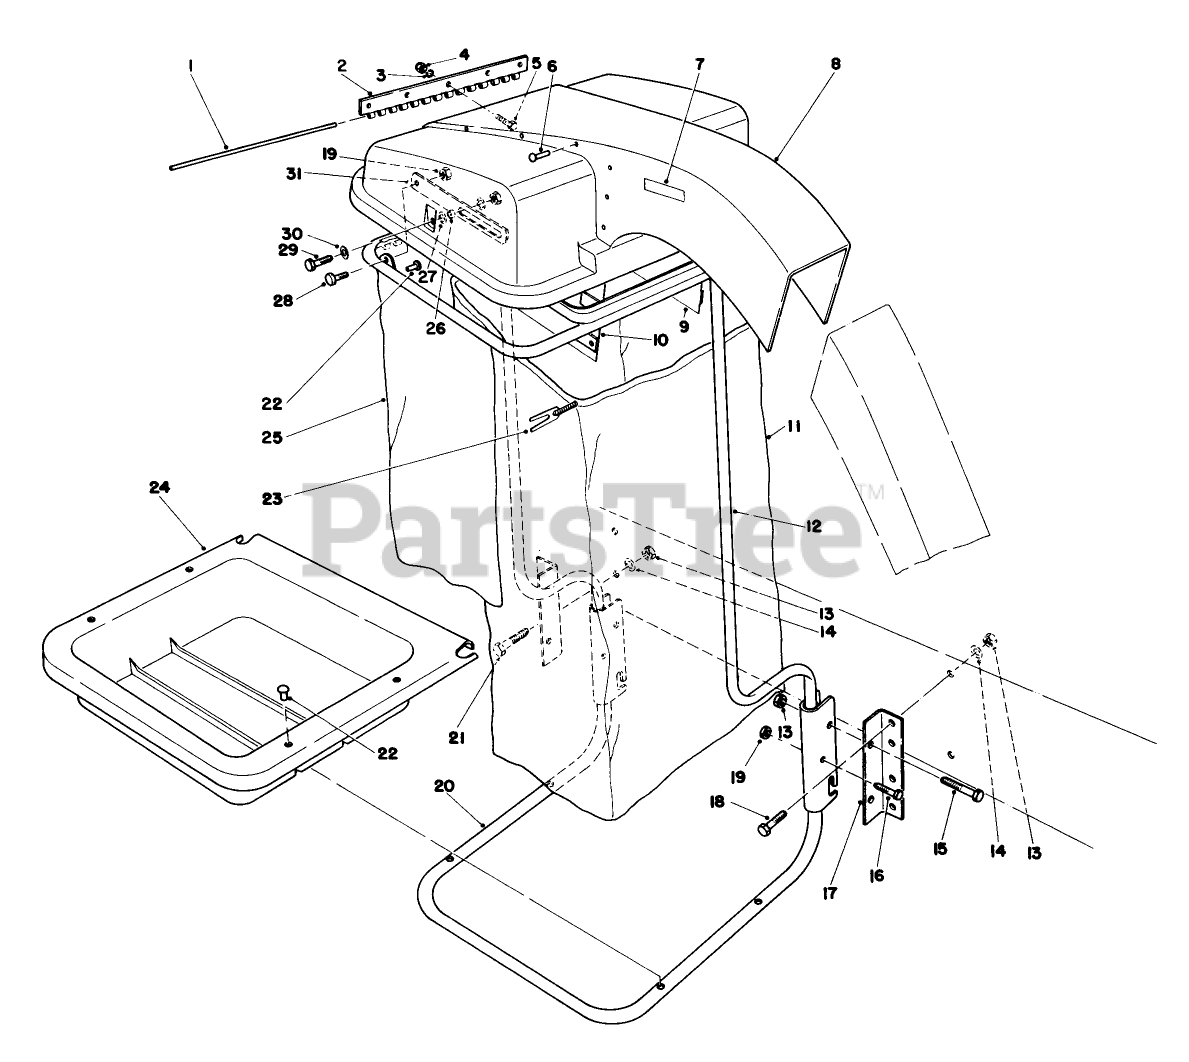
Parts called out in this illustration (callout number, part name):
1	HOOD HINGE PIN
2	Hinge-Half
3	WASHER-FLAT
4	NUT-LOCK, NI
6	RIVET-BLIND
7	Decal-Caution
8	Hood Assembly (Incl. Ref. #2-7, 9 & 10)
9	Screen Left Hand
10	Screen Right Hand
11	BAG-CLOTH, 32"
12	Support Tube Assy. Upper (Incl. Ref. #22 & 25)
13	NUT-LOCK, CONE
14	WASHER-FLAT
15	SCREW-HH
16	SCREW-HH
17	BRKT-FRAME B
18	SCREW-HH
19	NUT-LOCK, CONE
20	Support Tube Assy.-Lower (Incl. Ref. #22 & 24)
21	SCREW-HH
23	BAG CORD FASTENER
24	Tray Lower
25	Skirt-Bagging Frame
26	SPACER - PIVOT ARM
27	WASHER-FLAT
28	SCREW-HH
29	SCREW-HH
30	WASHER-FLAT
31	Stop-Hood
